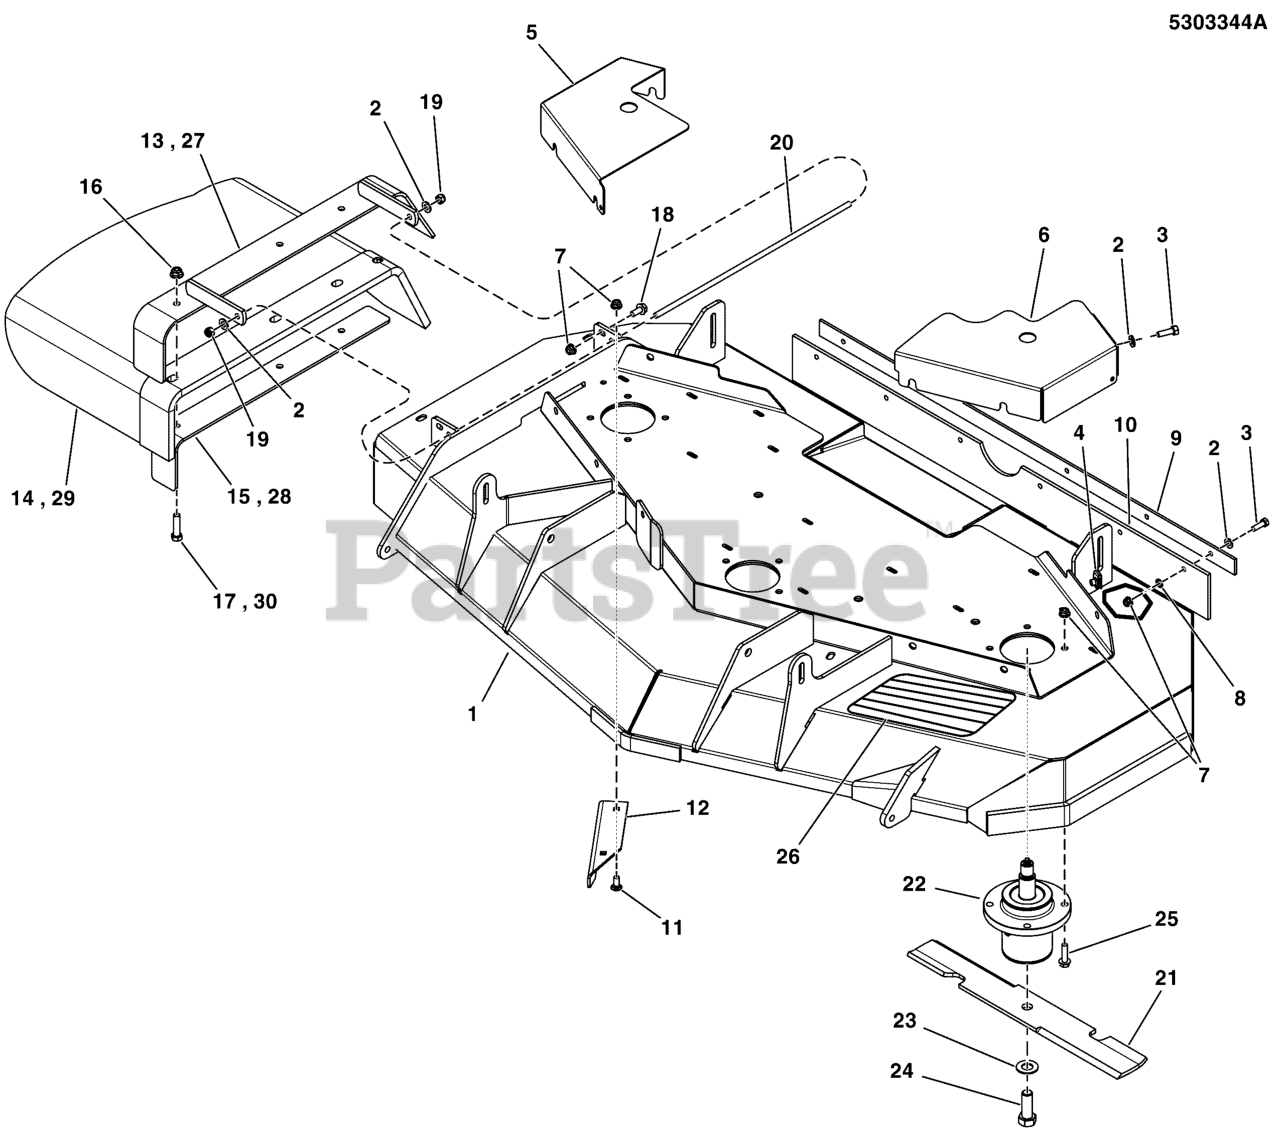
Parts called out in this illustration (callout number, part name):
1	DECK SHELL W/ DECALS, 52, F125XT (SV)
1	DECK SHELL W/ DECALS, F125XT-52, ANSI-EXP
2	WASHER, 5/16" SAE
3	BOLT, 5/16-18 X 1 GD5 YZ
4	BODY CLIP, 5/16-18-7GA MATERIAL
5	GUARD, RH 52", 560/700/125
6	GUARD, 52 DECK, LH - RED
7	NUT, 5/16-18 HEX NYLOCK FLANGE
8	5/16 PUSH-ON NUT RETAINER, STL, CZ
9	PLATE, SUPPORT - BLK
10	FLAP, STRIPER, 52 DECK
11	BOLT, 5/16-18 X 3/4, CARRIAGE
12	PLATE, DEFLECTOR, 52 DECK - BLK
13	WELD, FRAME CHUTE, 52 - BLK
14	CHUTE, Discharge
15	SUPPORT, DISCHARGE CHUTE, 52 - BLK
16	NUT, 3/8-16 HEX NYLOCK FLANGE
17	BOLT, 3/8-16 X 1-1/2" GD5 CZ
18	BOLT, 5/16-18 X 3/4 GD5
19	NUT, 5/16-24 HEX NYLON LOCK
20	ROD, MOUNT, CHUTE 61, CZ
21	BLADE, 18 X .25 X 2.5, 1 X 3.5 (SET OF 3)
22	ASSM, SPINDLE, LOW PROFILE
23	WASHER, 5/8 GRADE 8, YZ
24	BOLT, 5/8-11 X 1-3/4 GD8
25	BOLT, 5/16-18 X 1 1/4 FLANGE
26	SAFETY WALK, 4.00 X 7.50
27	WELD, MOUNT, DISCHARGE CHUTE - BLK
28	SUPPORT, DISCHARGE CHUTE - BLK
29	CHUTE, RUBBER DISCHARGE (5104442)
30	BOLT, 3/8-16 X 1-1/2, CARRIAGE, GD5, CZ
